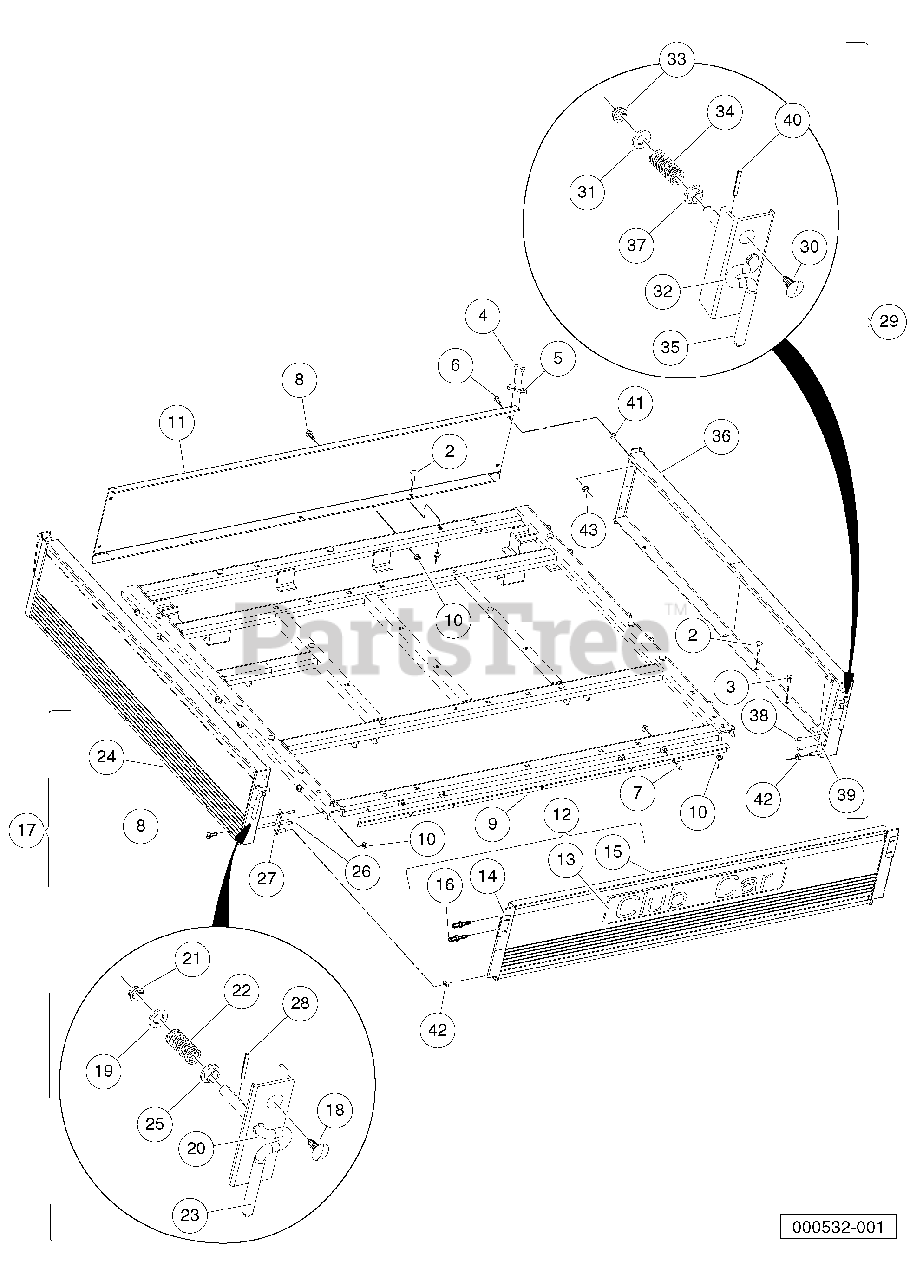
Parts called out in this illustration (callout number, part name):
1	Install, Box Bed
2	Bolt, Carriage, 5/16-18 X 1.00
3	Screw, 5/16-18 X 1.00 Hex Cap
4	Screw, #10 Truss-Head Torx
5	Cap, Corner
6	Screw, 1/4-20 X 0.75 Torx Truss-Head
7	Stud, Self-Clinching Flush Head
8	Screw, 5/16-18 X 0.88 Torx Truss-Head
9	Box Bed Tailgate Angle
10	Locknut, 5/16-18 Hex Flange
11	Panel, Front
12	Tailgate Asm
13	Decal, Logo, Tailgate
14	Plate, Tailgate Latch Wear
15	Tailgate Weldment
16	Rivet, 3/16 X .400 Blind
17	Asm, Panel, Side, Left
18	Barrel - Plastic
19	Washer, 3/8 Flat
20	Latch, Tailgate, Left-Hand
21	Bushing, Snap-In
22	Compression Spring Latch Tilt
23	Grip, Tilt Latch Hand
24	Weldment, Panel, Side, Left
25	Bushing, Nylon
26	Rivet, 1/4 X 0.30, Blind
27	Asm, Tlgt, Mtg Brkt, Ca Lh
28	Pin, 1/8 X 1.00 Split Roll
29	Asm, Panel, Side, Right
30	Barrel - Plastic
31	Washer, 3/8 Flat
32	Latch, Tailgate, Right-Hand
33	Bushing, Snap-In
34	Compression Spring Latch Tilt
35	Grip, Tilt Latch Hand
36	Weldment, Panel, Side, Right
37	Bushing, Nylon
38	Rivet, 1/4 X 0.30, Blind
39	Asm, Tlgt, Mtg Brkt, Ca Rh
40	Pin, 1/8 X 1.00 Split Roll
41	Washer, 1/4 Type A Narrow Flat
42	Bushing, Nylon
43	Locknut, 1/4-20 Nylon Insert
